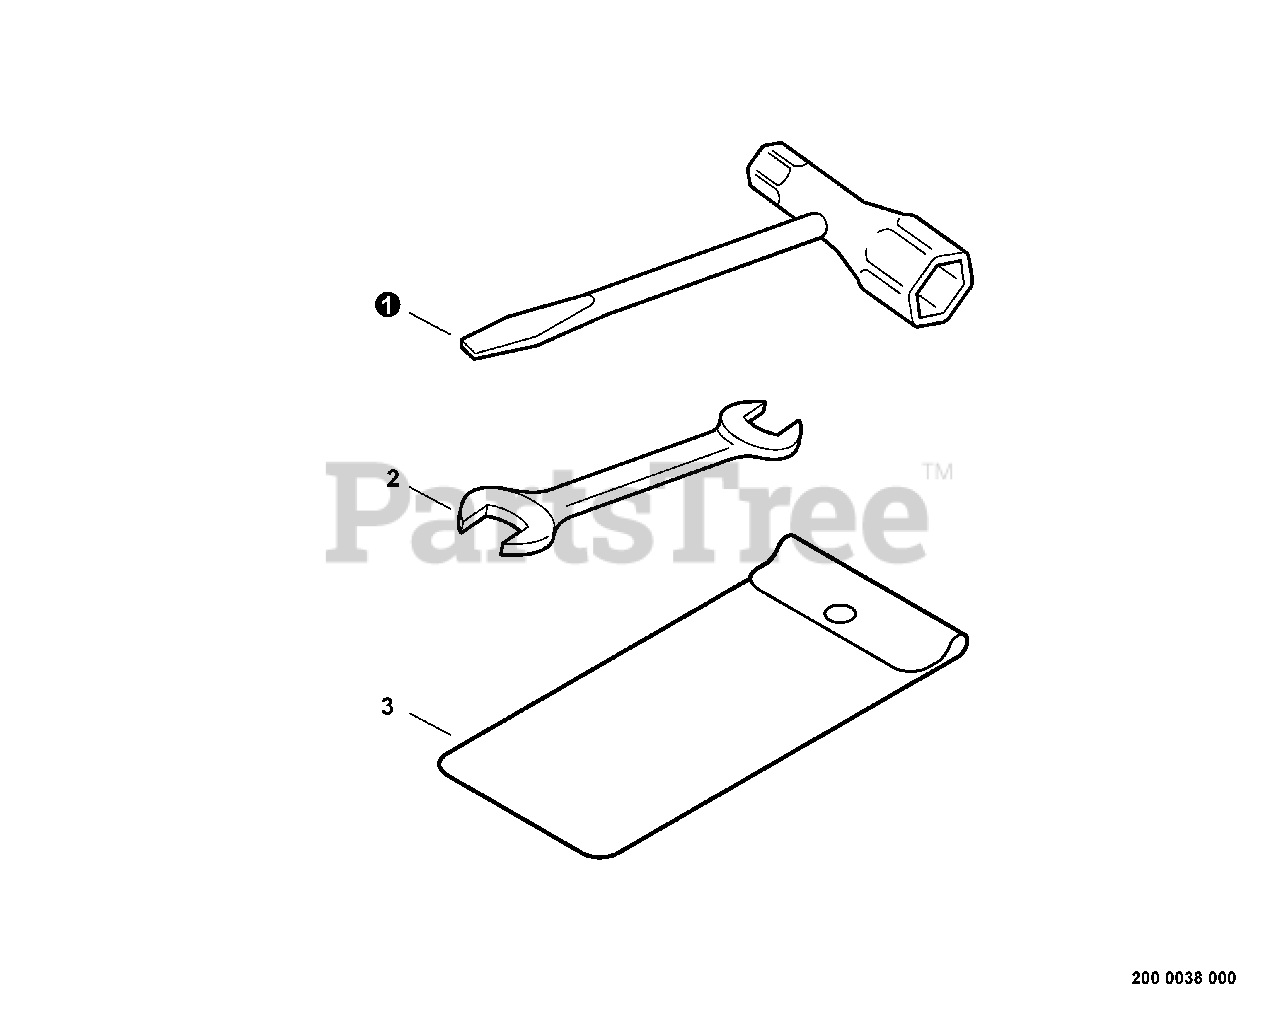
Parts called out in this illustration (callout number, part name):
1	T-WRENCH 17x-19 L200
2	SPANNER 8×10
3	BAG, TOOL
